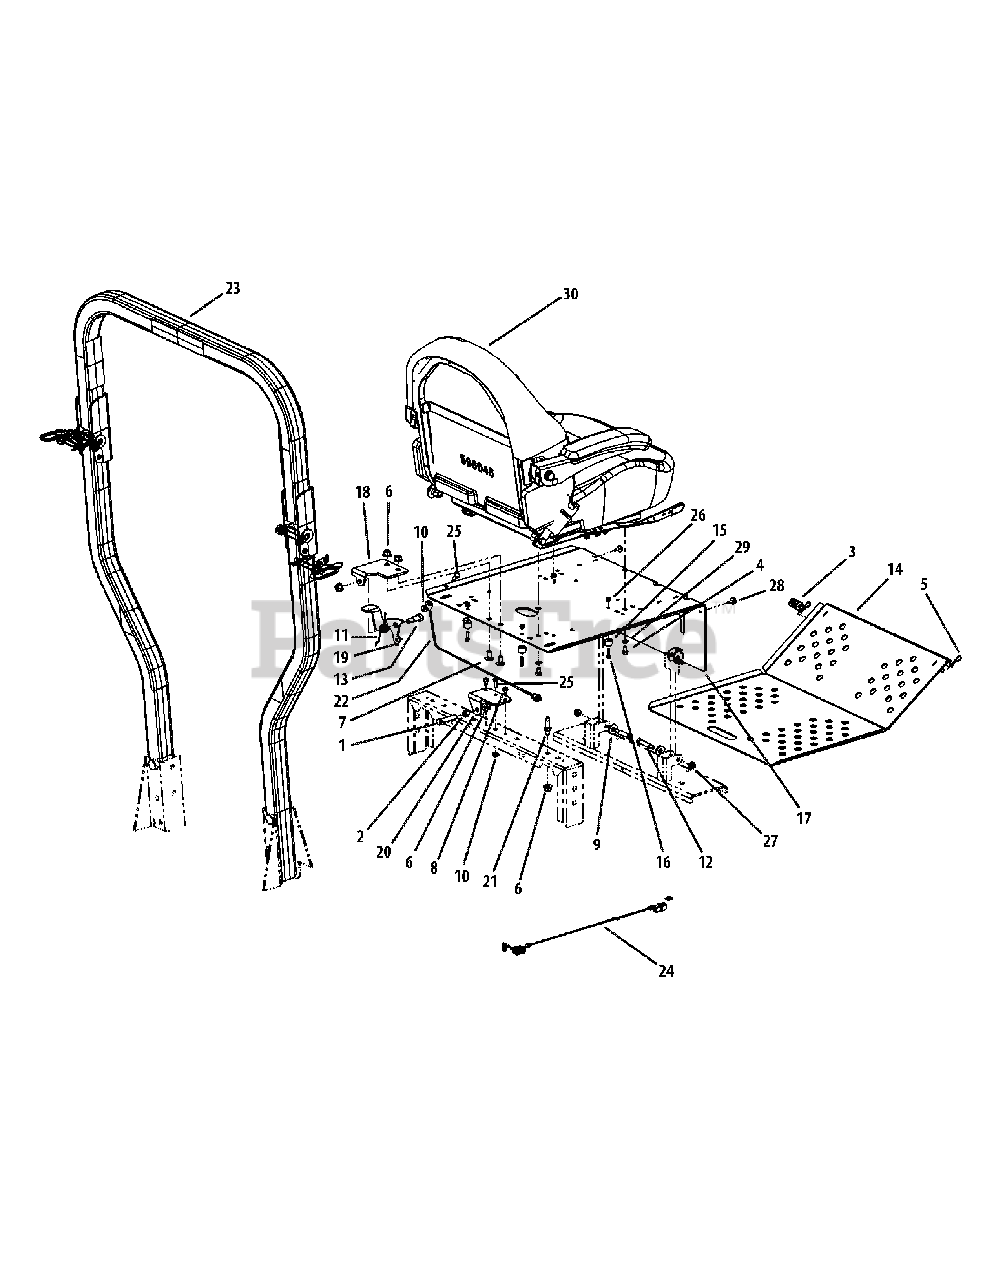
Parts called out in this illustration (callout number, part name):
1	Hex Cap Screw 3/8-16 x 2.00
2	Hex Nut, 3/8-16
4	Hex Cap Screw, 5/16-18 x 1/2
5	Hair Pin, 3/8-1/2
6	Flange Lock, Hex Nut, 3/8-16
7	Carriage Bolt, 3/8-16 x .75 Long
8	Screw, TT, 1/4-20, 0.5, Hex Washer
9	Flat Washer, .406 ID, 1.0 OD, .105
10	Lock Nut, 1/4-20
11	Deck Lift Spring, Left Hand
12	Shoulder Bolt, .375 x 1.50
13	Shoulder Bolt, 1/2 x 3/4, 3/8-16
14	Floor Panel Assembly
15	Rubber Stop with Washer
16	Standard Cap Screw, #10-24 x .75
17	Seat Plate Assembly
18	Seat Latch Bracket
19	Latch Lever Bracket
20	Latch Bracket
21	Adjustable Stud
22	Cable Support
23	Foldable Rops Assembly
23	Pin, Lock
24	Wire Harness Adaptor
25	Screw, Hex, Cap, 1/4-20 x .75
26	Nut, #10-24, Nylon Lock
27	Nut, 5/16-18, Flangelock
28	Rubber Bumper, .62 OD x .22 Thick
29	Lock Washer, 5/16
